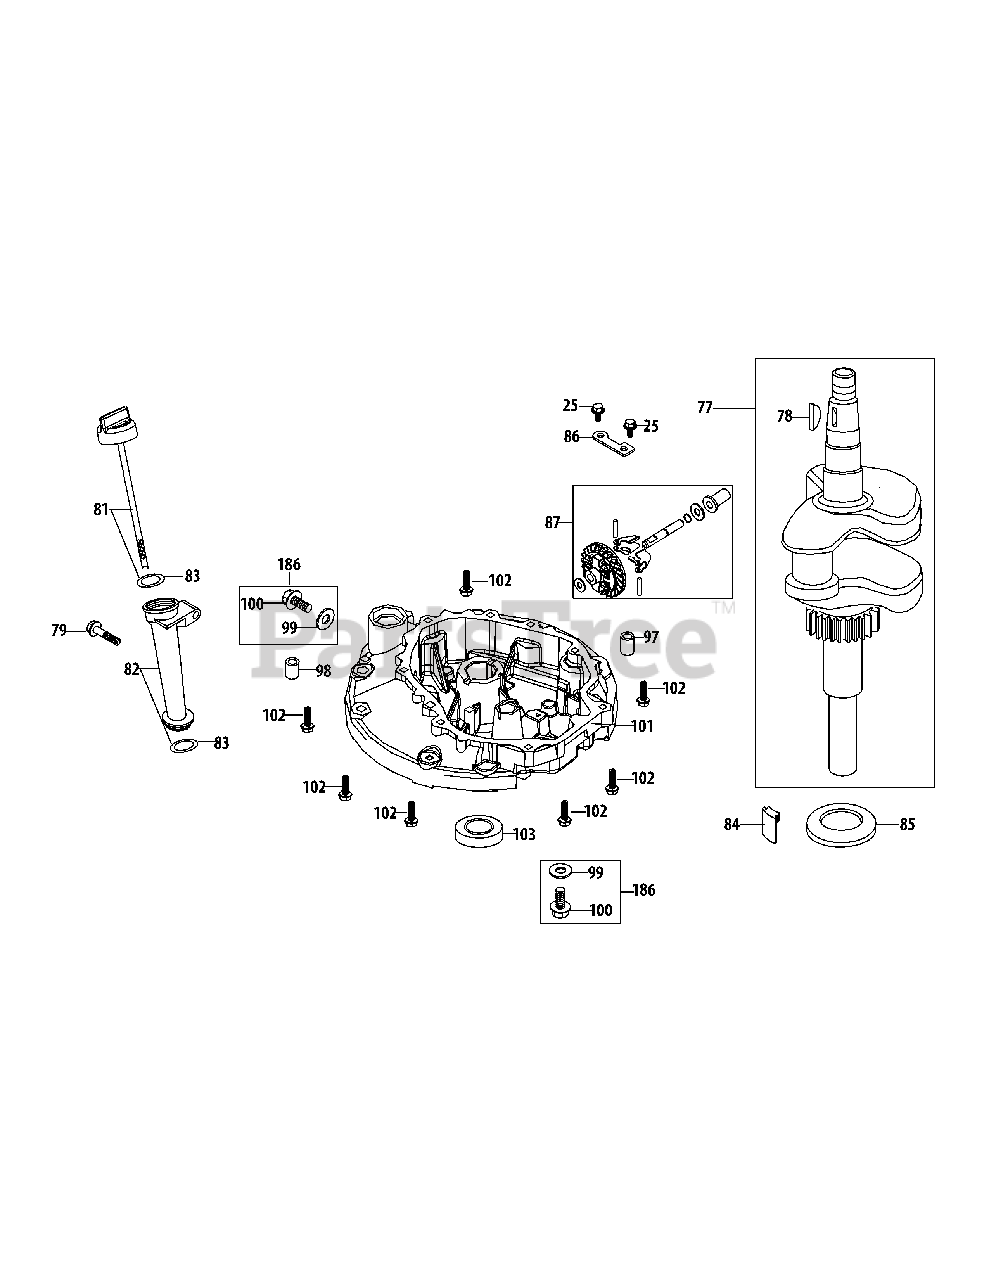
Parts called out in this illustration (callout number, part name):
25	Bolt M6X14
77	Crankshaft Assembly
78	Flywheel Key
79	Bolt M6X35
81	Dipstick Assembly
82	Oil Fill Tube
83	Dipstick / Oil Fill Tube O-Ring
84	Oil Return Seal
85	Crankshaft Thrust Washer
86	Governor Gear Mounting Plate
87	Governor Gear/Shaft Assembly
97	Crankcase Cover Dowel Pin 7×14
98	Crankcase Cover Dowel Pin 9×14
99	Oil Drain Plug Washer
100	Oil Drain Plug
101	Crankcase Cover
102	Bolt M6X28
103	Lower Crankshaft Seal
186	Oil Drain Plug & Washer Ass'y
